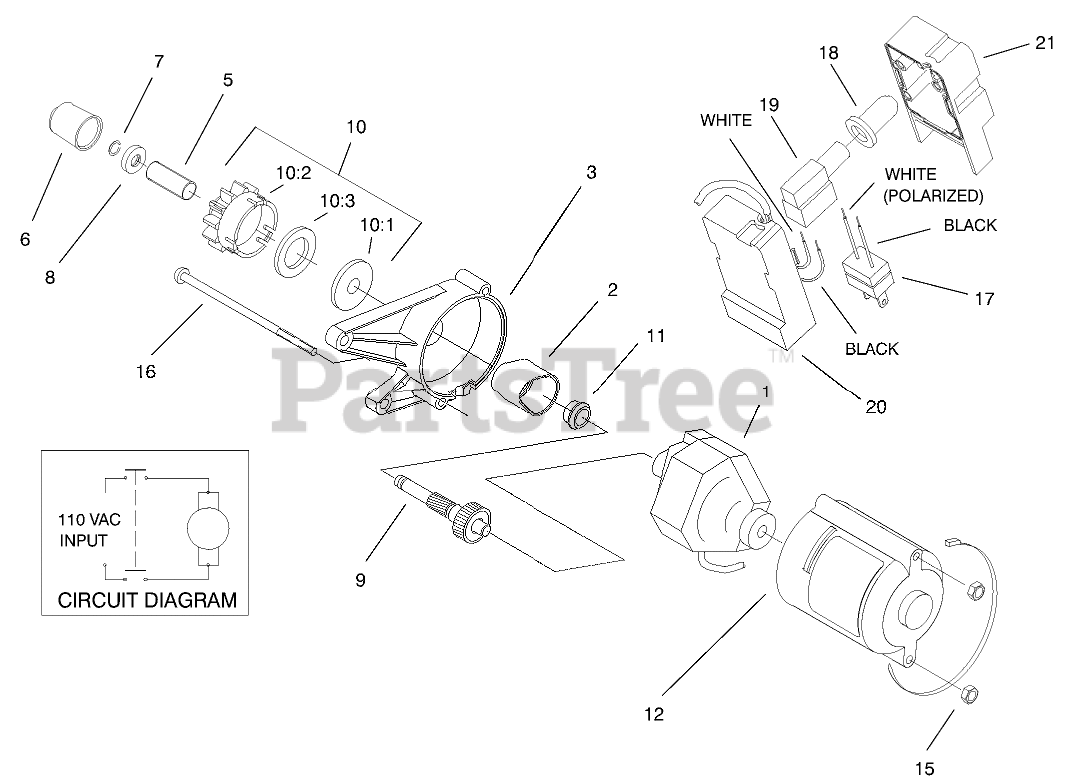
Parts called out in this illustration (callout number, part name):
1	STARTER MOTOR ASM
2	COVER-GEAR
3	HOUSING-UPPER, STARTER
5	SPRING
6	CAP-PINION
7	RING-LOCK
8	STOP-PINION
9	SHAFT/GEAR ASM
10	PINION ASM
10:2	PINION
10:3	RING-RUBBER
11	BUSHING
12	HOUSING-LOWER, STARTER
15	NUT-LOCK, NI
17	PLUG-POWER
18	BOOT-SWITCH
19	SWITCH-STARTER
20	SWITCH-BASE, HOUSING
21	HOUSING-CAP, SWITCH
